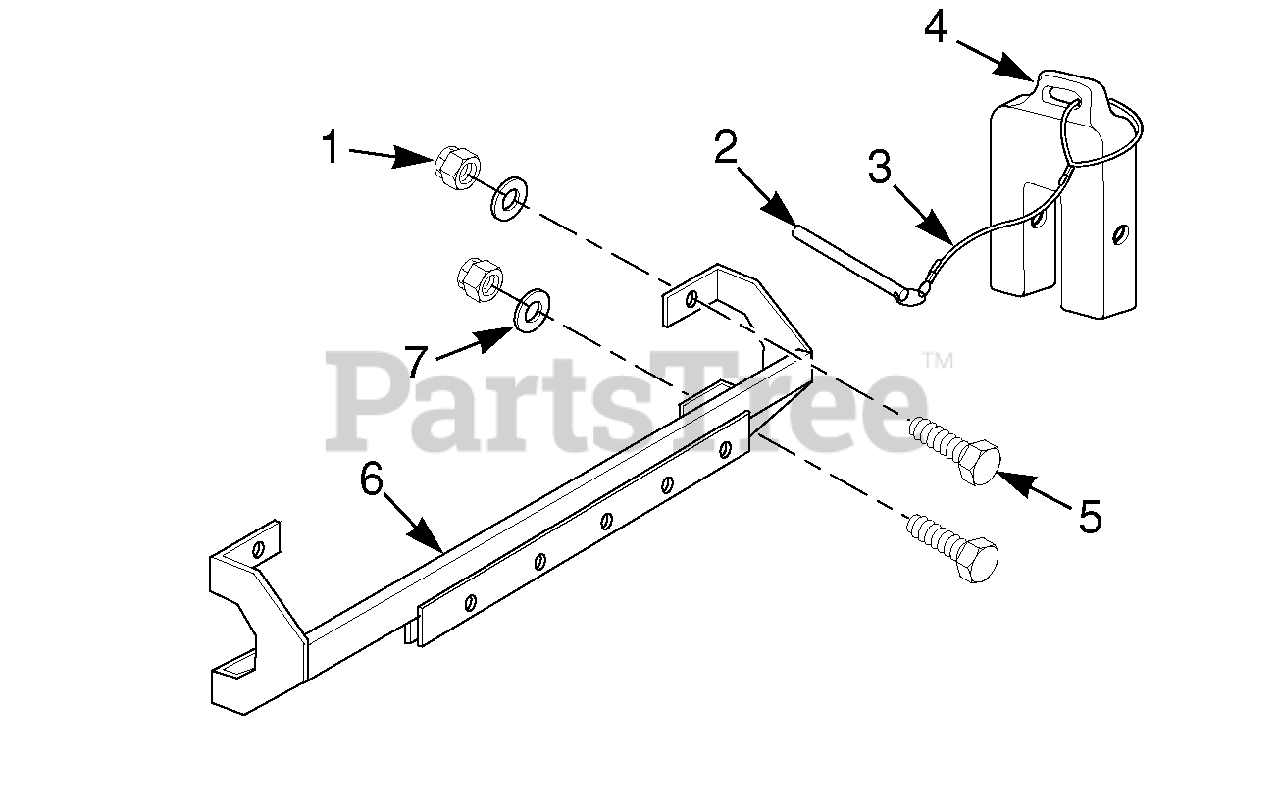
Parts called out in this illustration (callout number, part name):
1	Nut, Elastic Stop 7/16-14
2	Pin, 1/2 x 6-1/4"
3	Lanyard, Weight Pin
4	Weight Assembly
5	Bolt, Hex Head 7/16-14 x 1-3/4"
6	Support Weldment, Front Weights
7	Flatwasher, 7/16-.500 x 1.250 x .083
